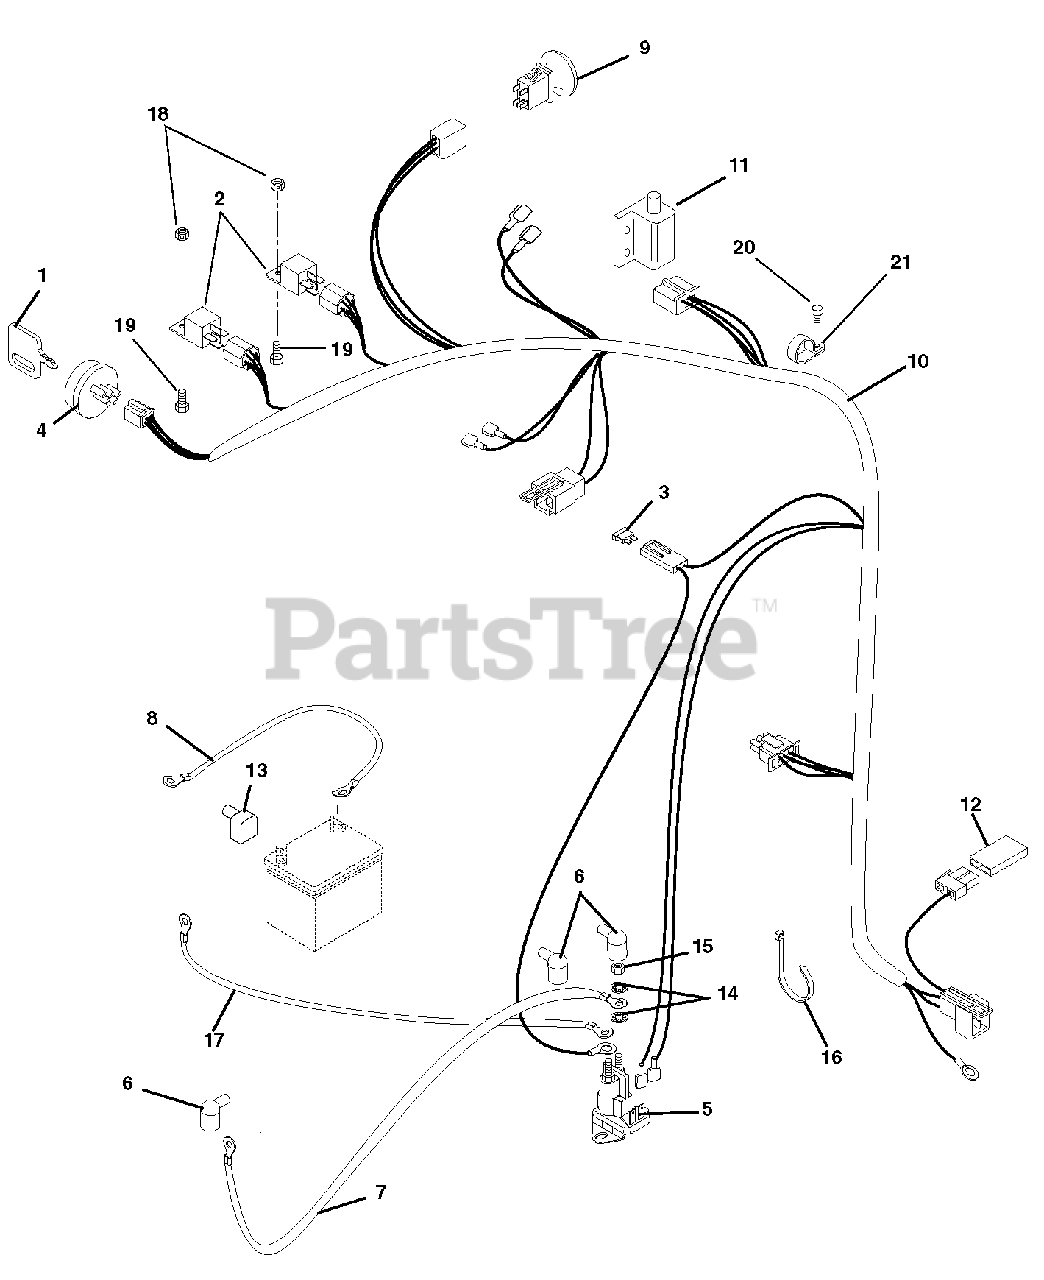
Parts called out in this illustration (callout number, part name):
1	Key with Cap
2	Relay
3	Fuse, 30 AMP
4	Key Switch
5	Solenoid
6	Boot, Eyelet Terminal
7	Starter Cable
8	Cable, Ground .25 x 13.00 x .31
9	Switch, Clutch With Retainer
10	Harness, ZTXL/ZoomXL
11	Switch, Double Pole N.O. / N.O.
12	Diode, Connector Shell
13	Insulator
14	Washer, Locking .31
15	Nut, Jam .31-24
16	Cable Tie
17	Starter Cable
18	Nut, Locking Nylon With Insert 10-24
19	Screw, Hex Washer Head Machine 10-24 x .75
20	Screw, Tapping Hex Washer Head Thread Rolling .38-16 x .50
21	Clamp, Cushioned Steel .75
